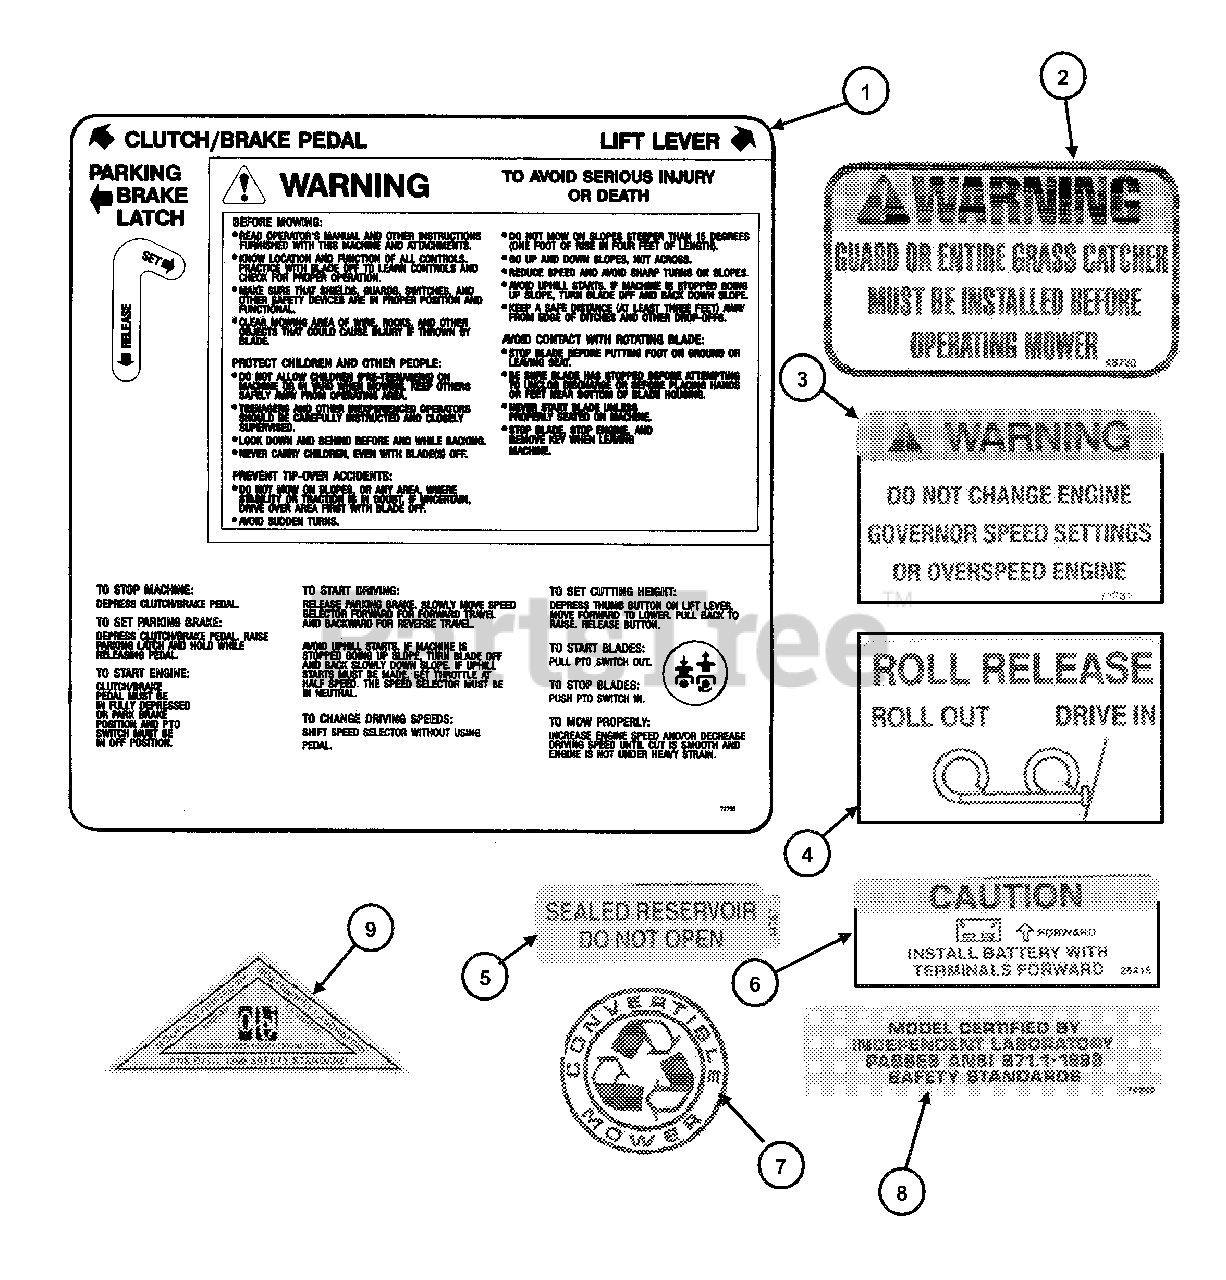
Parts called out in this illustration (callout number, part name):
1	DECAL, Instruction Frame Top
2	DECAL, Chute/Deflector
3	DECAL, Warning Speed Setting
4	DECAL, Roll Release
5	DECAL, Hydro Reservoir
6	DECAL, Caution Battery Location
7	LOGO, Medallion
8	DECAL, Certification, B71.1-1998
9	DECAL, OPEI
